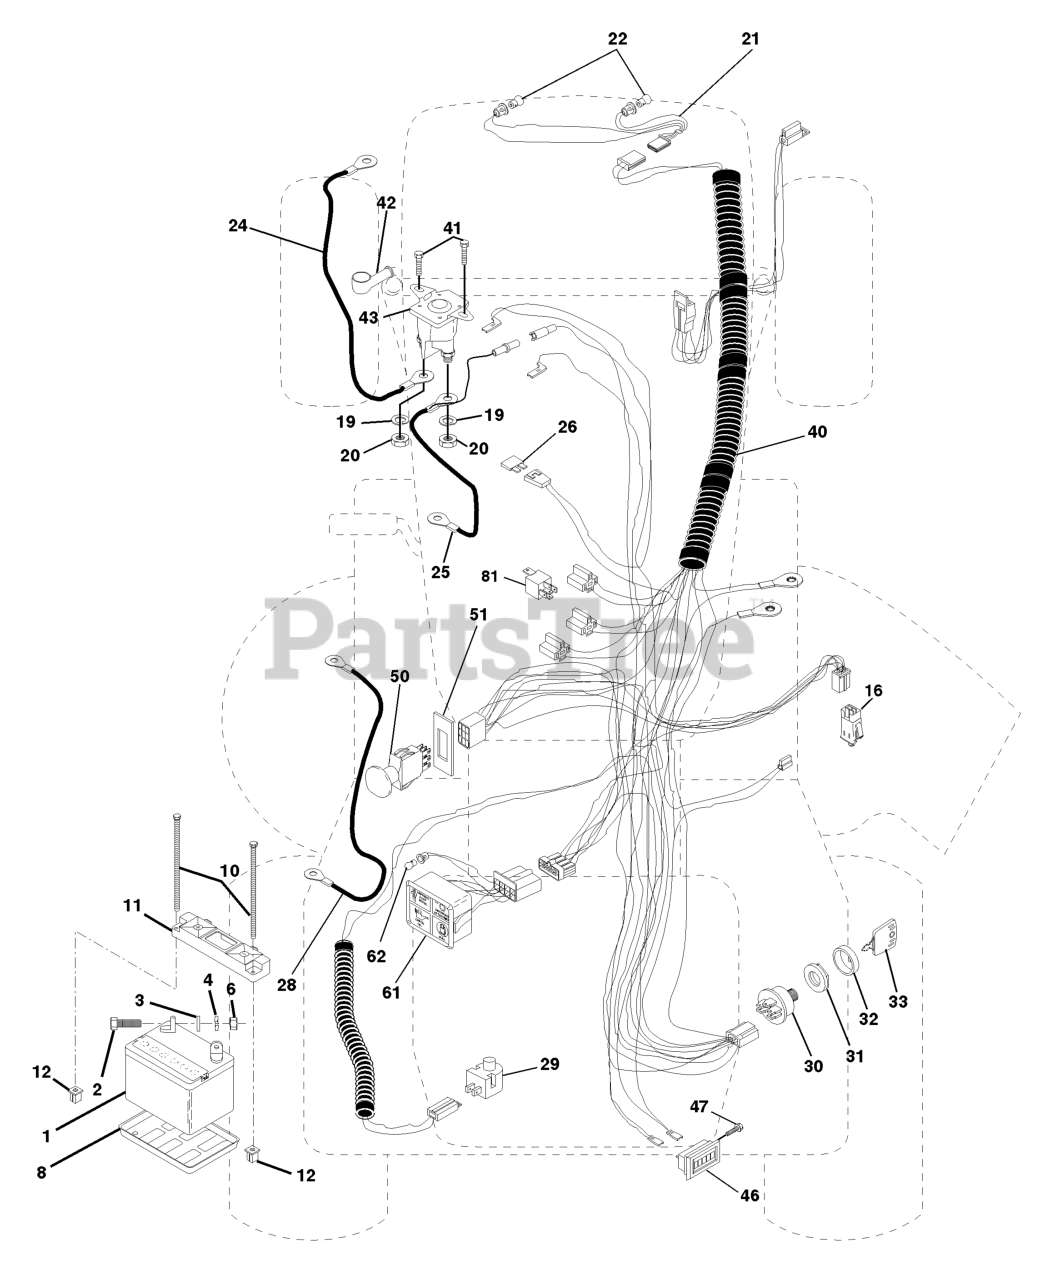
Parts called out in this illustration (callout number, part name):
1	BATTERY 12V .35 AMP
2	BOLT.HEX.1/4.X.3/4.DICHROMATE
3	LOCKWASHER
4	WASHER
6	NUT
8	BATTERY TRAY T
10	BOLT 1/4-20 X 7.5
11	BATTERY HOLDDOWN FRONT MOUNT
12	NUT, PUSH NYLON 1/4" BATTERY
16	SWITCH INTERLOCK
19	LOCKWASHER
20	NUT
21	HARNESS LIGHT SOCKET
24	CABLE, STARTER
25	CABLE, BATTERY
28	CABLE, GROUND
29	PLUNGER SWITCH (COLOR:OLIVE)
30	SWITCH.IGNITION.4.POSITION
31	NUT IGNITION
32	COVER SWITCH KEY
33	KEY.MOLDED.GENERIC
40	HARNESS.IGNITION
41	SCREW
42	TERMINAL COVER
43	SOLINOID
46	HOUR METER T
47	Screw #10-24 x 1/2
50	SWITCH PTO 3 PDT
51	FRAME RETAINING RING
61	LIGHT PACKAGE
62	BULB LIGHT T
81	RELAY.ASSY.T
